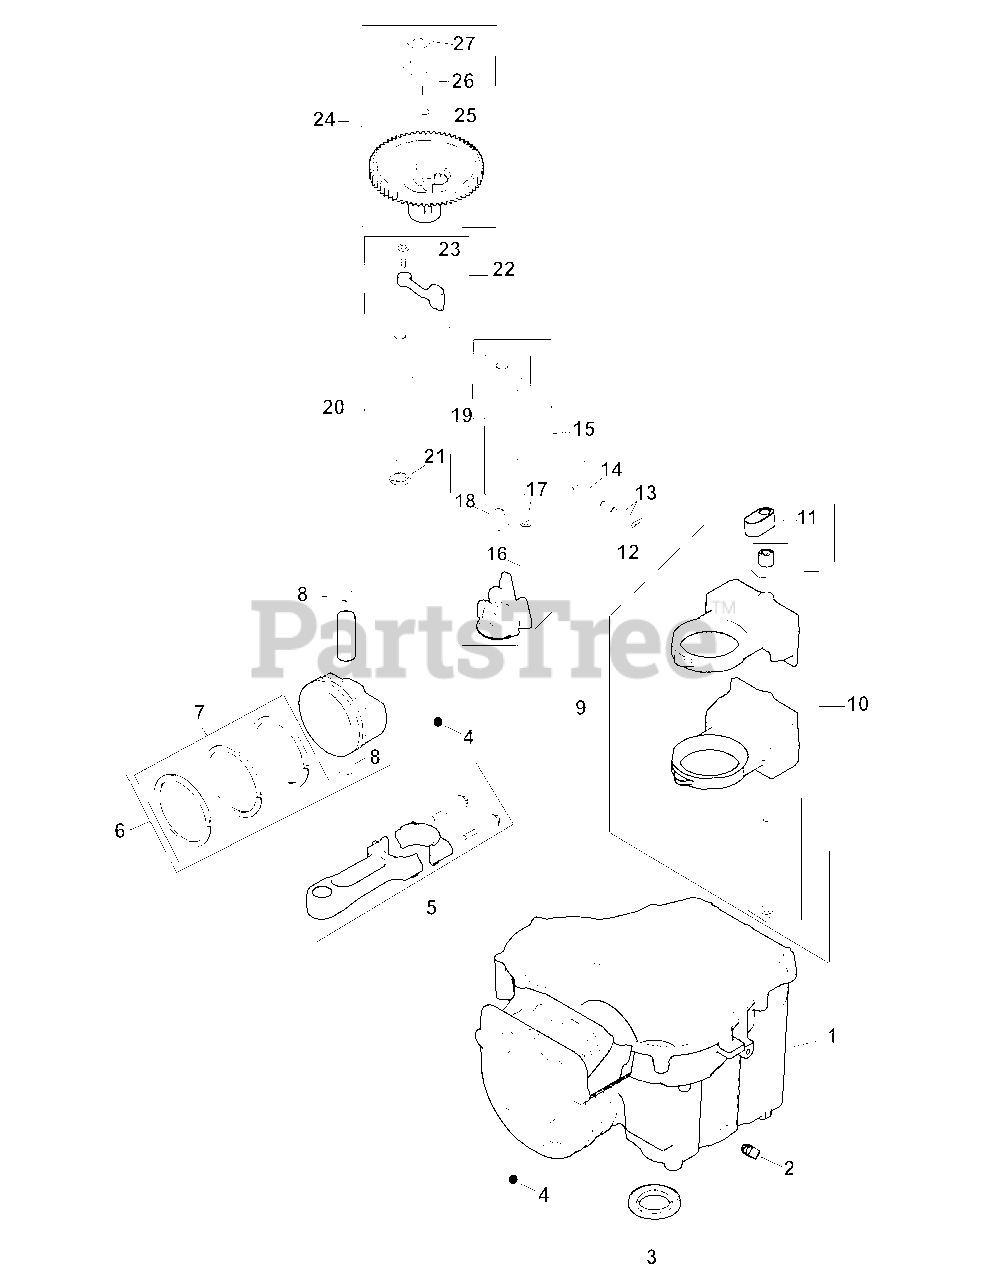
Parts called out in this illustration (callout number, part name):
1	Crankcase
2	Pipe Plug Sq. hd. 3/8"
3	Oil Seal
4	Check Valve Ball
5	Connecting Rod (Std.)
6	Piston w/Ring Set (Std.)
7	Ring Set (94 mm)
8	Piston Pin Retainer
9	Balance Weight Kit
10	Screw/Guide Pin Kit
12	Hitch Pin Clip
14	Governor Cross Shaft
15	Oil Pump Assembly (17-20)
16	Oil Pump Screw Spacer
17	Oil Pump Screw
18	Oil Pump Outlet Seal
20	Exhaust Cam Center Shaft
21	Thrust Washer
22	Cam Lever Assembly (24)
23	Shoulder Screw
24	Cam Gear Assembly (26-28)
26	ACR Weight
27	ACR Thrust Washer
